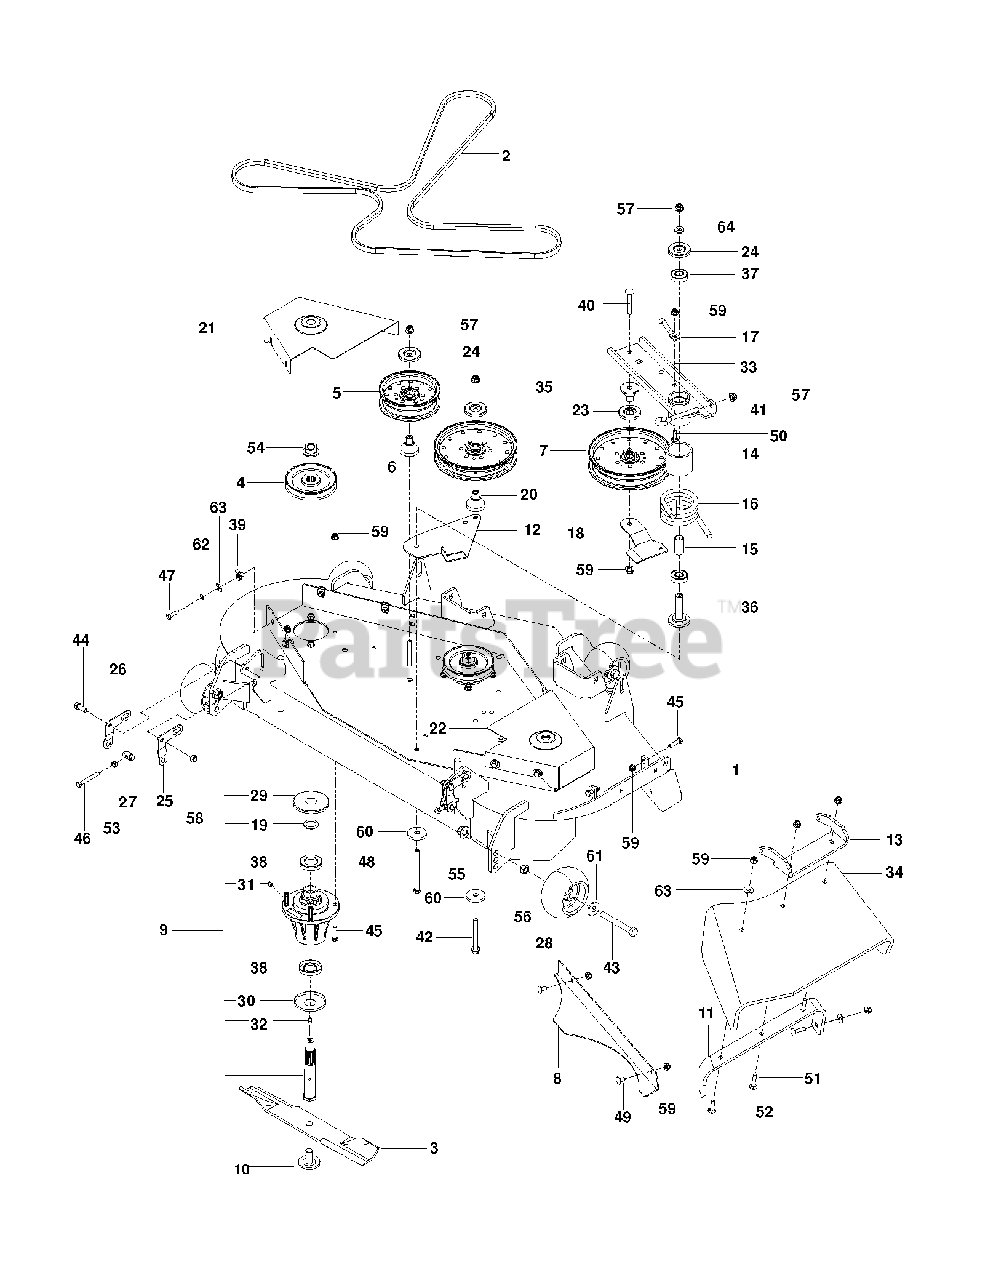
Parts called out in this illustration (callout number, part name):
1	DECK W/DECALS DX148
2	BELT DECK DX148
4	PULLEY 42-48
5	IDLER PULLEY
6	PULLEY - 7" NARROW
7	PULLEY - IDLER 7"
10	BLADE BOLT/WASHER
11	BRKT, REINF - CHUTE 52/61"
12	BRACKET, SPRING STOP
13	PIVOT BRACKET - CHUTE
15	SPACER, IDLER BEARINGS
18	BELT GUIDE, BLK
19	MACHINE BUSHING
20	BEARING, IDLER STANDOFF
21	BELTSHIELD - L.H. BLUE
22	BELTSHIELD - R.H. BLUE
23	SHIELD, DUST
24	DUST SHIELD
27	TRUNION, PITCH
29	TOP DUST CAP
30	BOTTOM DUST CAP
31	PLUG-VENTED
33	IDLER.ARM.BLACK
34	CHUTE DISCHARGE 48"
35	BEARING, IDLER ARM
36	BEARING, IDLER PIVOT
37	BEARING, BALL
38	SHAFT SEAL
39	U-CLIP 5/16-18 NUT RETAINER
40	CARRIAGE BOLT 3/8-16 X
43	HCS 1/2-13 X 4 GR 5 ZD
44	HCS 3/8C X 1
45	HCS 5/16C X 1 1/4
46	HCS 5/16-18 X 2 1/2 TPBLT
47	HCS 5/16C X 3/4
48	HCS 3/8-16 X 4-1/2 GR 8 ZD
49	CARRIAGE BOLT 5/16C X 5/8"
50	RHSSNB 5/16C X 1.0
51	RHSNB 5/16-18 X 1-1/2 GR 5 ZD
52	BOLT, CARRIAGE 5/16X1-1/4
53	NUT 5/16C HEX
54	NUT FLANGE 3/4-16
55	NUT, 1/2-13 HEX FLG NYLOC ZD
56	NUT 1/2 HEX JAM
57	NUT 3/8-16 HEX FLG NYLOC ZD
58	NUT 3/8-16 NYLOC
59	5/16-18 NYLOC FLANGE NUT
60	SPINDLE WASHER
61	WASH USS FLAT 1/2
62	WASH 5/16 DISC SPRING ZD
63	WASHER 5/16 FLAT
64	WASHER, 3/8 THICK
